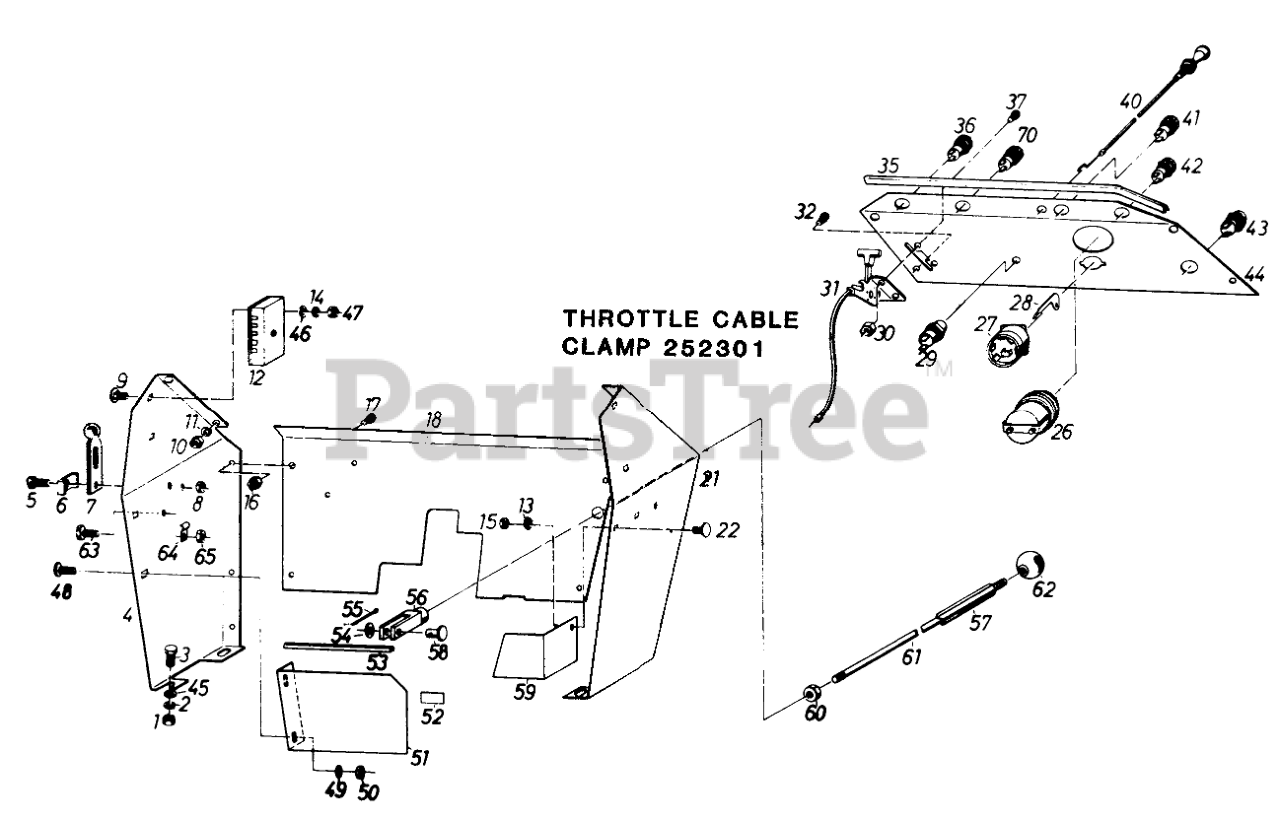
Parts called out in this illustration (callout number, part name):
2	Lockwasher
4	Right Hand Part
6	CLAMP
7	FASTENING STRAP
11	Lock Washer
12	Fuse Block
13	Washer
14	Lock Washer
17	Screw
18	Rear Part
21	Left Hand Part
26	Hour Meter
27	Ignition-Light Switch
28	Switch Key
29	Starter Push Button
31	Throttle
32	Screw
35	Cushion
36	Park Brake Light
40	Choke Control
41	Park Brake Light
42	Engine Temp. Light
43	Horn Button Switch
44	Instruments Board
45	Washer
46	Washer
49	Spring Washer
51	Protection
52	Limiting Devise
53	Profile Cleat Red
54	Washer
55	Split Pin
59	Belt Protection
61	Hydraulic Shift Rod
62	Hydraulic Control Knob
63	Screw
64	Clamp
70	Engine Temp. Light
